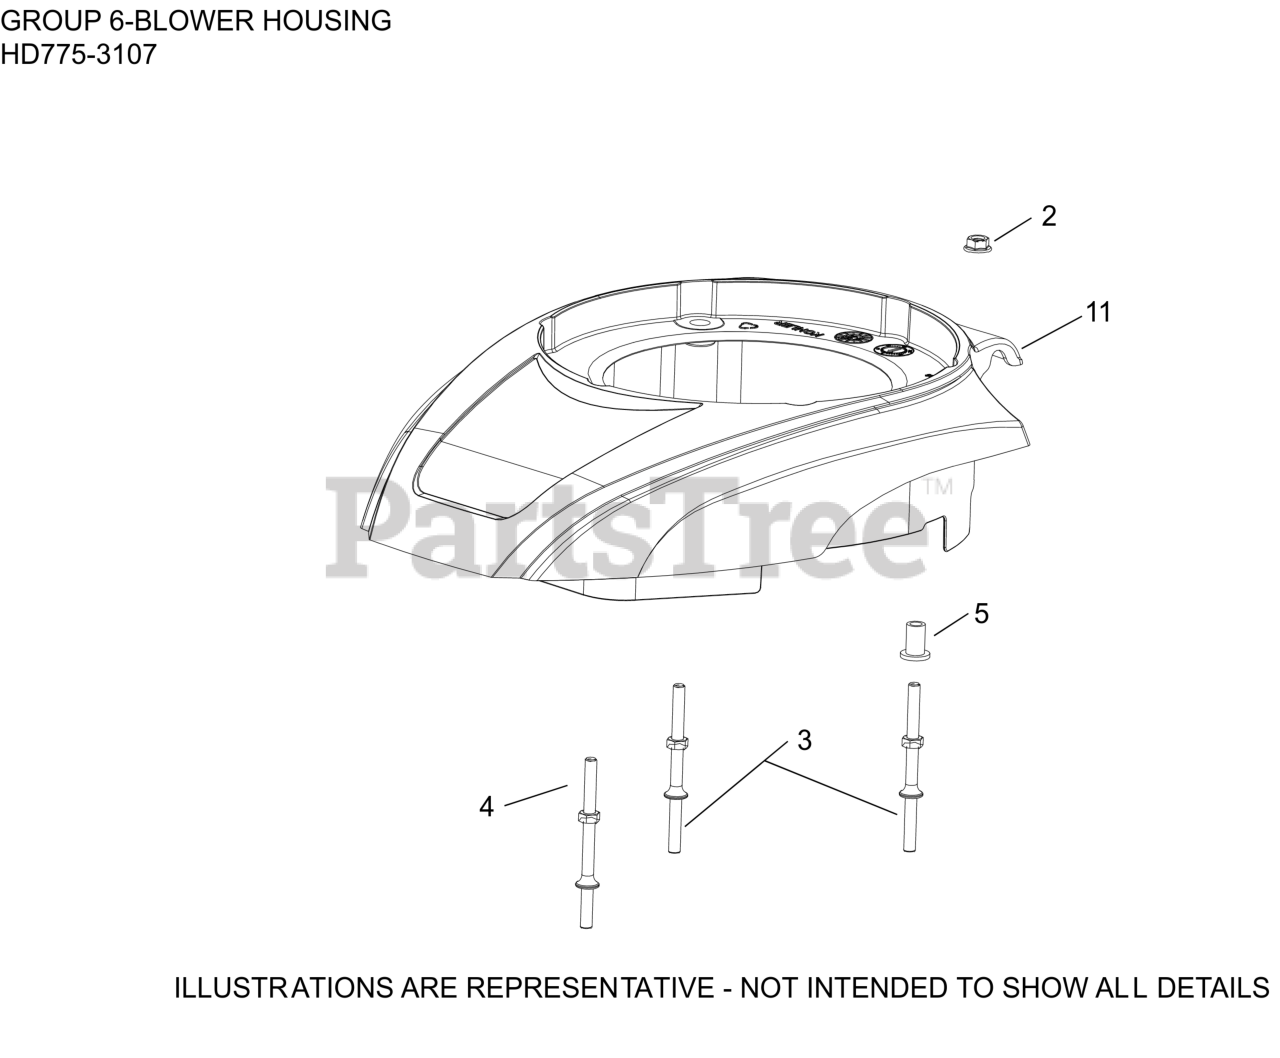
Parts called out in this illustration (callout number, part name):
2	NUT, HEX FLANGE (M6) - USE 14 100 16-S
3	STUD-USE 14 072 25-S
4	STUD-USE 14 072 26-S
11	COVER, ENGINE
